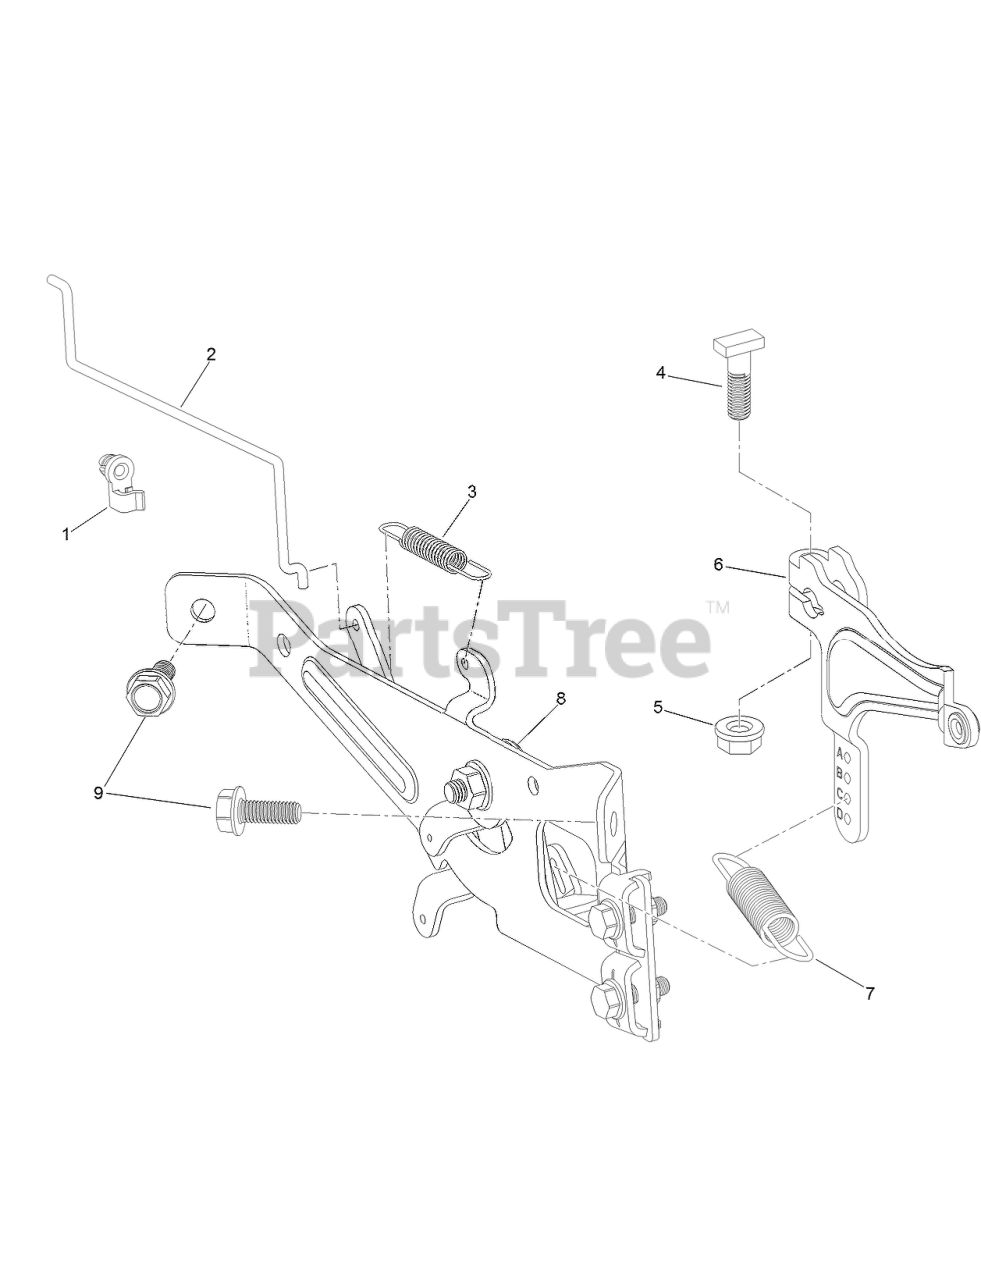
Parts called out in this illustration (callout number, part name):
1	CLIP-LINKAGE
2	LINKAGE-CHOKE
3	SPRING-GOVERNOR
4	BOLT-ARM, GOVERNOR
5	NUT-FLANGE
6	ARM-GOVERNOR
7	SPRING-GOVERNOR
8	PLATE-CONTROL
9	SCREW-HHF
